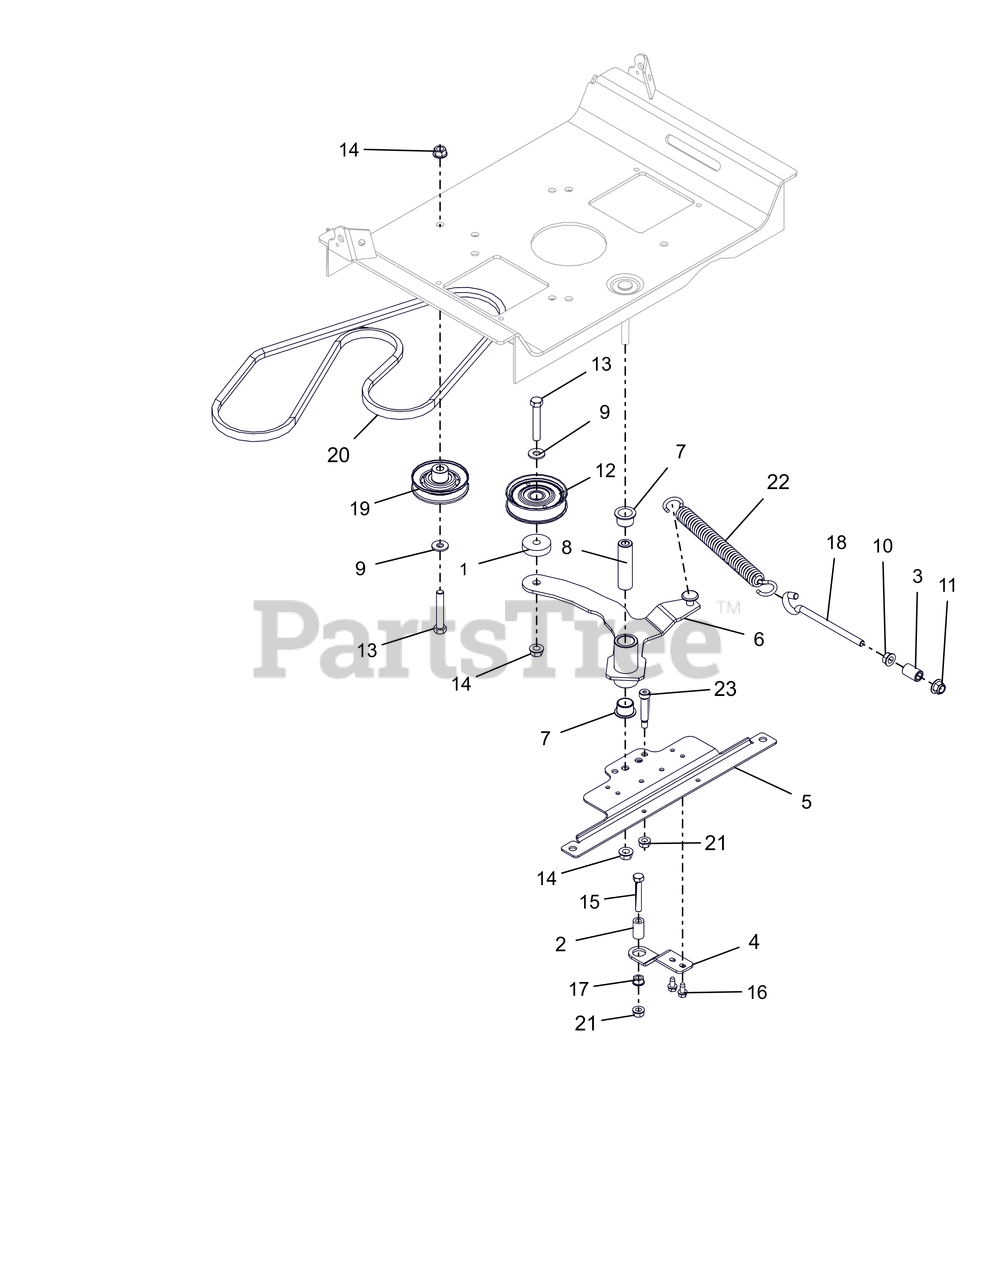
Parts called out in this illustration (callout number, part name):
1	SPACER, .39 X 1.50 X .380
2	SPACER, RUBBER 5/16 IDX1.0 LG
3	SPACER, .375X.625X.970 (PM)
4	BRKT, CLUTCH STOP
5	BRKT, DRIVE IDLER MOUNTING
6	WLDMT,GRD DRIVE IDLER ARM-LGR
7	BSHG-FLG 0.75X0.875X.625X1.125
8	BUSHING, SLEEVE .38X.750X2.78
9	WSHR,FLT .375X.875X.083 ZCC
10	NUT, SPNLK-FLG .38-16 G5 ZCC
11	NUT,NYL-FLG .38-16 GF ZCC
12	IDLER, FLAT - 3.05" X .75"
13	BLT,HEX .38-16X2.25 G5 ZCC
14	NUT-LK-TOP-FLG .38-16 ZC120
15	BLT, HEX .31-18X2.00 G5 ZCC
16	SCR-TAP .25-20X.50 HWH ZCC
17	NUT,SPNLK-FLG .31-18 G5 ZCC
18	BOLT,.38-16 X 4.25-.62 DIA EYE
19	IDLER, V-3.000 OD
20	V-BELT, A-RAW EDGE
21	NUT-LK-TOP-FLG .312-18 GF ZCC
22	SPRING, EXTENSION
23	BLT-SHLDR .38X1.5X.31-18 SLT Y
